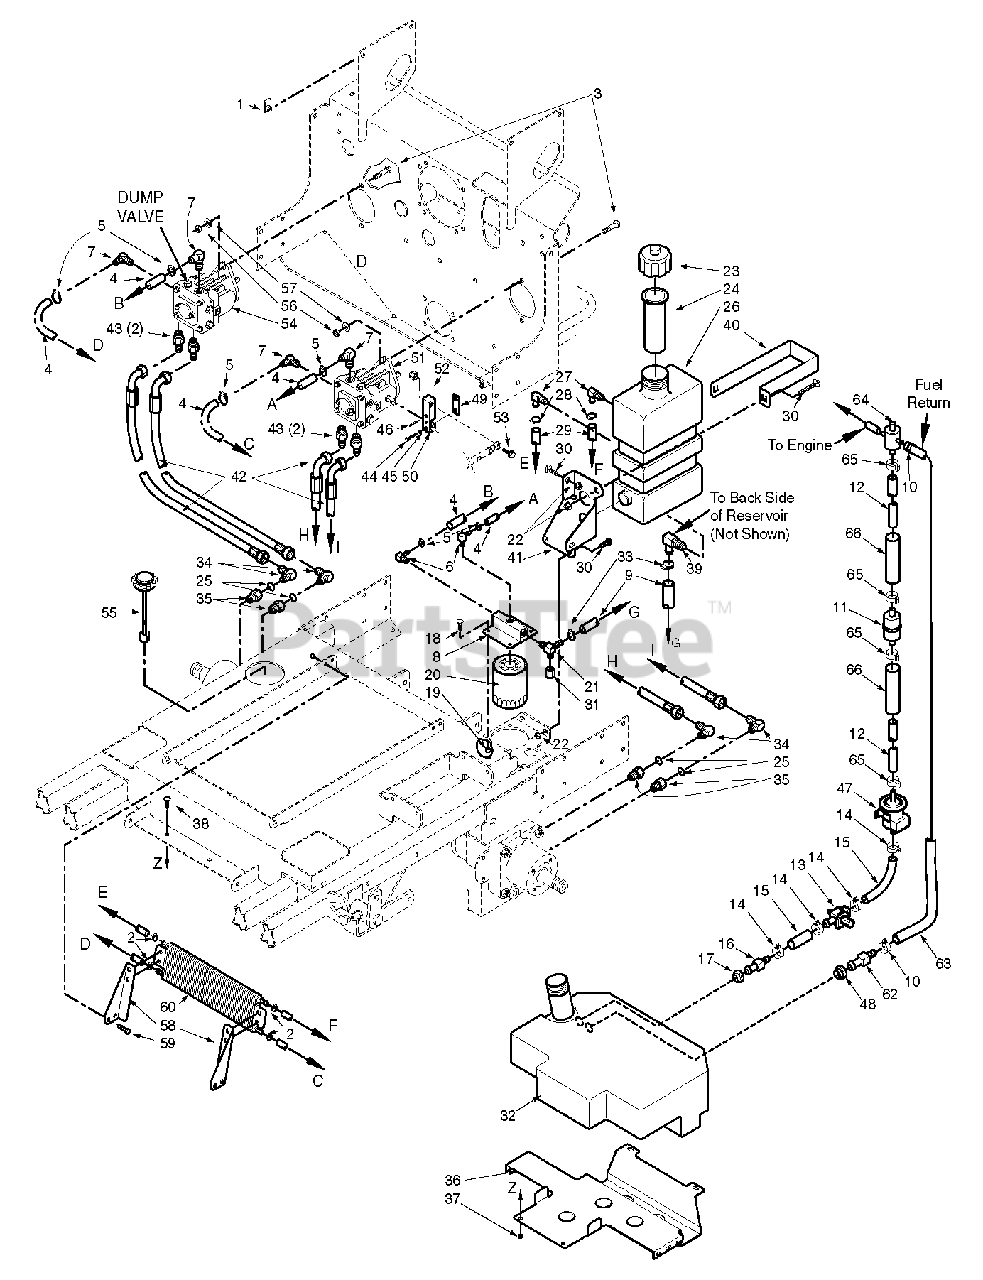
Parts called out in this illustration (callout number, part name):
1	U-Nut 1/4-20
2	Hose Clamp, 0.69" Dia.
3	Bolt, Hex Hd. 1/4-20 x 2.0"
4	Hose, 3/8" I.D. Pushlock
5	Clamp, Hose 1/2"
6	Elbow, 90 Degree - 1/4" NPT x 3/8" Hose
7	Elbow, 90 Degree - 9/16" O-ring x 3/8" Hose
8	Oil Filter Base
9	Hose Assy., 1/2" I.D. (Tank to Filter Base)
10	Clamp, Fuel Hose 1/4" Hose I.D.
12	Fuel Hose, 5/16" I.D. Non-Perm.
13	Valve, Shutoff
14	Clamp, Fuel Hose 5/16" Hose I.D.
15	Fuel Hose, 5/16" I.D. Non-Perm.
16	Hose Fitting w/Screen
17	Bushing
18	Bolt, Hex Hd. 5/16-18 x 1.0" Zinc
19	Nut, Serr. Flng. 5/16-18
20	Oil Filter
21	Tee, 3/4 O-ring x JIC x 1/2" Hose
22	Nut, Hex Elastic Stop 1/4-20
23	Cap, Hydraulic Tank
24	Insert, Filler Neck
25	O-Ring
26	Oil Reservoir Assembly
27	Elbow, 90 Degree .38" Hose
27	Bushing, .56" Dia. Viton
28	Hose Clamp, 0.69" Dia.
29	Hose, 3/8" I.D., Pushlock
30	Screw, Phillips Head, 1/4-20
32	Fuel Tank Assembly
33	Clamp, Hose
34	Elbow, 90 Degree, 7/8-14 THD
35	Bushing, 7/8-14 JIC x 3/4-16 O-Ring
36	Support Bracket, Fuel Tank
37	Nut, 5/16-18 Serr. Flng.
38	Bolt, Carriage 1/4-20 x 3/4"
39	Elbow, 90 Degree
39	Bushing, .78" Dia. Viton
40	Strap, Hydraulic Tank
41	Support Bracket, Hydraulic Tank
42	Hose Assembly, Pump
43	Union, 3/4-16 JIC x 3/4-16 O-ring
44	Bolt, Hex Hd., 1/4-20 x 1-14"
45	Lockwasher, 1/4" Spring
46	Roll Pin, Spring 3/16 x 3/4"
48	Bushing
49	Clamp Plate, Pump Control
50	Block, Pump Control
51	Pump, Left Hand, BDP-16A
52	Nut, Hex, Elastic Stop 3/8-16
53	Bolt, Hex Hd., 3/8-16 x 1-1/4
54	Pump, Right Hand, BDP 16A
55	Cap, Fuel Tank w/Gauge
56	Nut, Hex Elastic Stop 3/8-16
57	Flatwasher, 3/8" (.391 x .938 x .105") Grd. 8
58	Mounting Bracket - LH, Oil Cooler
58	Mounting Bracket - RH, Oil Cooler
59	Bolt, Hex Hd. 5/16-18 x 3/4"
60	Cooler, Oil
61	Clamp, .69" Dia.
62	Fitting, Hose
63	Hose, 1/4" Fuel Line Non-Perm.
65	Fuel Clamp, 5/16" Oetiker
66	Shield, Flexible
